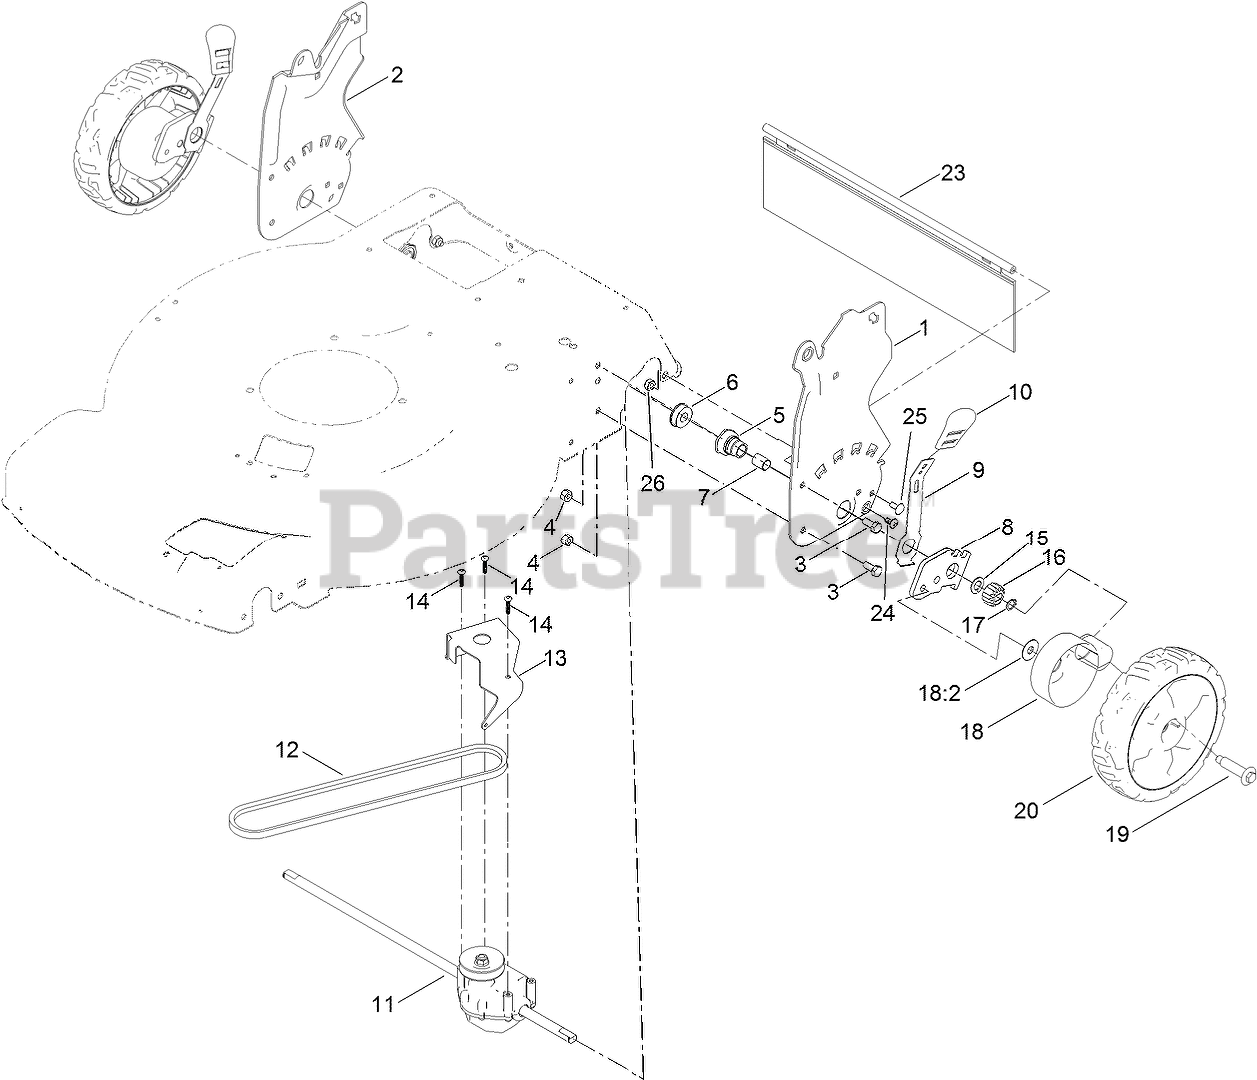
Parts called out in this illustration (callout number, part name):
1	PLATE-HOC, LH
2	PLATE-HOC, RH
3	SCREW-HH
4	NUT-LOCK, NI
5	RETAINER-BUSHING, HOC
6	BEARING-BALL
7	BUSHING-SLEEVE
8	ARM-PIVOT, REAR
9	ARM-SPRING
10	KNOB-HOC
11	TRANSMISSION ASM
12	BELT-V
13	BRACKET-TRANSMISSION
14	SCREW-PLASTITE
15	WASHER-THRUST
16	GEAR-PINION, 15T
17	RING-RETAINING
18	GEAR COVER ASM
18:2	WASHER-STEPPED
19	BOLT-SHOULDER
20	WHEEL GEAR ASM, 8IN
23	SHIELD-TRAILING
24	SCREW-PTH
25	SCREW-CARR
26	NUT-LOCK, NI
